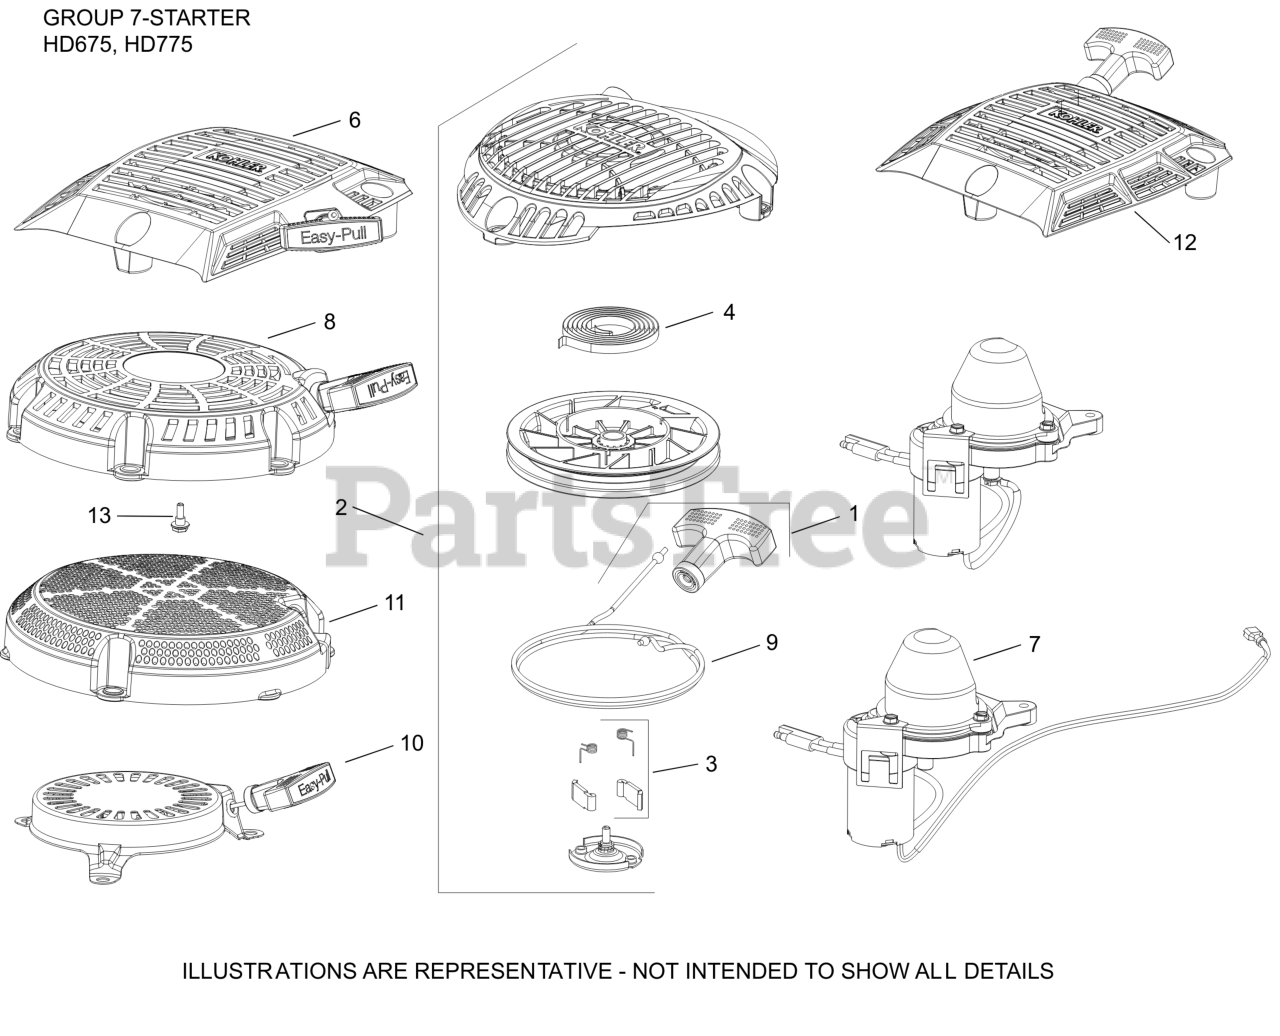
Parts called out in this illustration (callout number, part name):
1	KIT, STARTER ROPE W/HANDLE
2	STARTER ASSEMBLY, RETRACT
3	KIT, PAWL REPAIR
